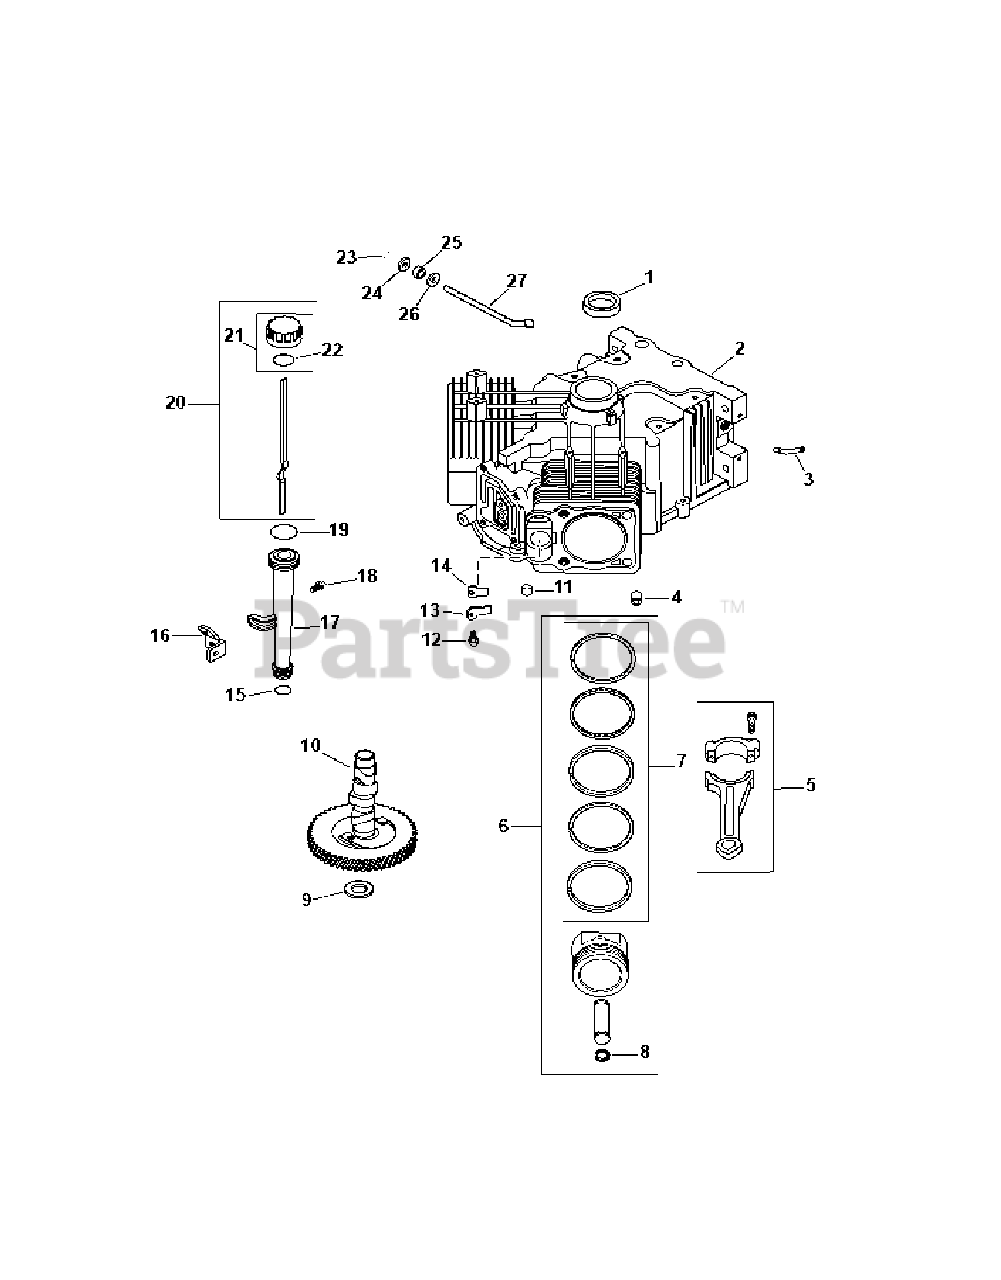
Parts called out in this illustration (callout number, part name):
1	Oil Seal
4	Split Dowel Pin
5	Connecting Rod (Std.)
5	Connecting Rod (.25)
6	Piston w/Ring Set Kit (Std.)
6	Piston w/Ring Set Kit (.08.)
6	Piston w/Ring Set Kit (.25.)
6	Piston w/Ring Set Kit (.50.)
7	Ring Set (Std. & .08)
7	Ring Set (.25)
7	Ring Set (.50)
8	Piston Pin Retainer
9	Shim (White)
9	Shim (Blue)
9	Shim (Red)
9	Shim (Yellow)
9	Shim (Green)
9	Shim (Gray)
9	Shim (Black)
10	Camshaft Kit
11	Cup Plug
13	Reed Retainer
14	Breather Reed
16	Oil Fill Tube Bracket
17	Oil Fill Tube
18	Screw
19	O-Ring Upper Fill Tube
21	Oil Fill Cap Kit
23	Ring Retainer
24	Plain 9mm washer
25	Oil Governor Shaft Seal
27	Governor Cross Shaft
